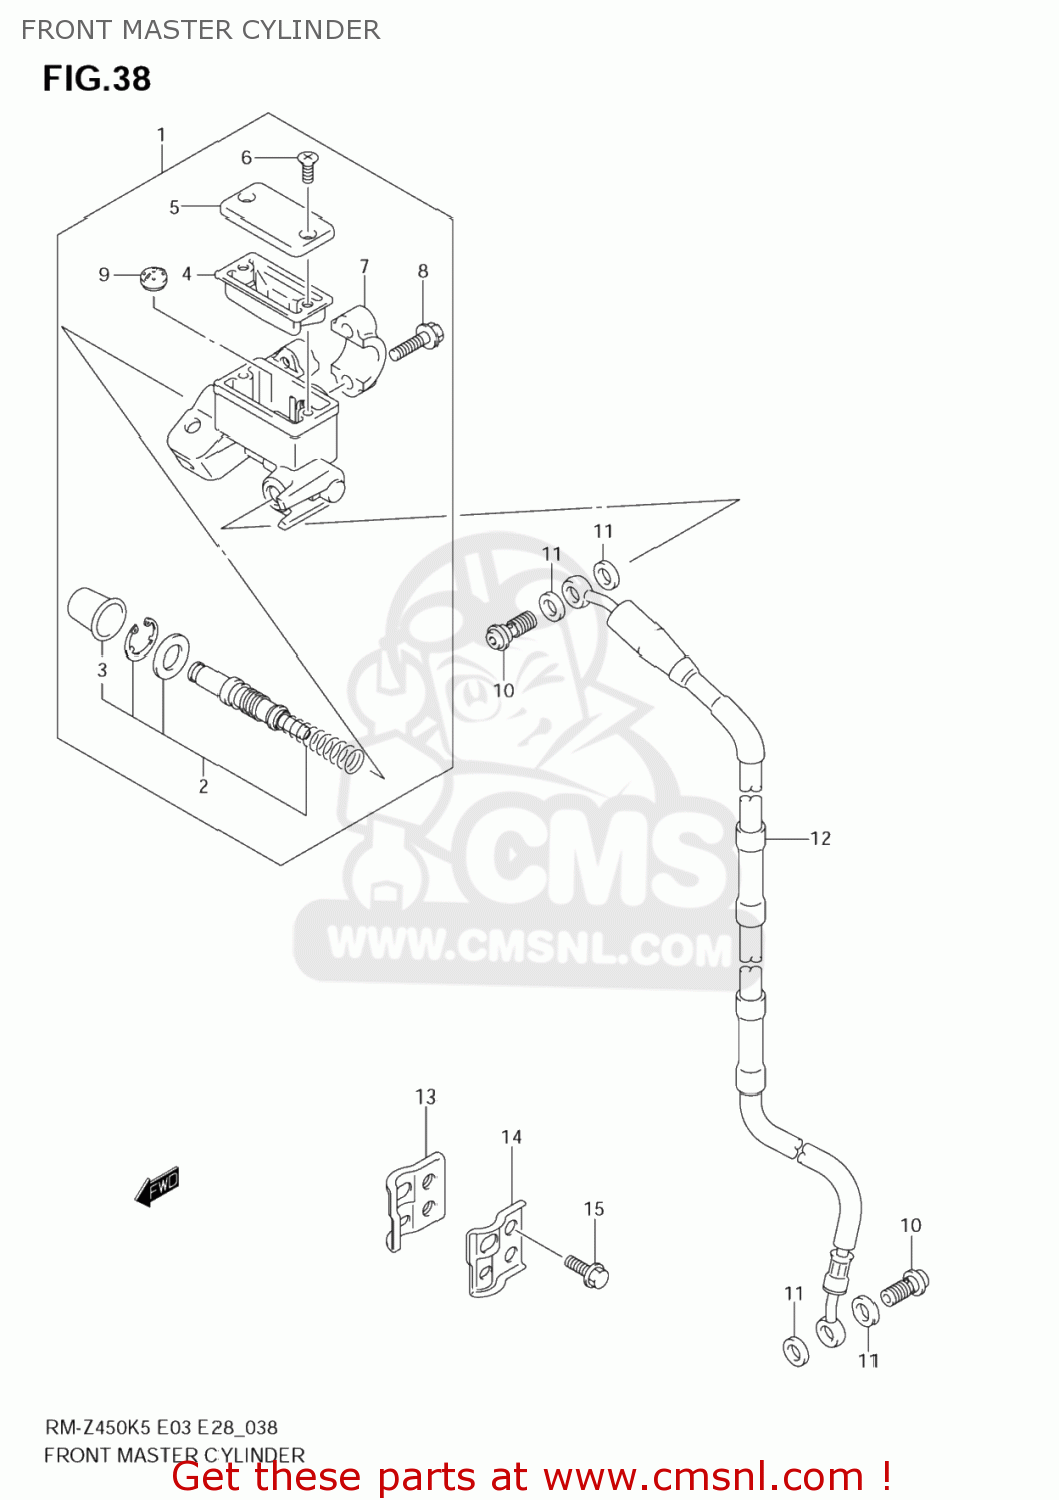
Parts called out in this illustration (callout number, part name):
1	CYLINDER ASSY,FR MASTER
2	PISTON & CUP SET
3	BOOT
4	DIAPHRAGM
5	CAP
6	SCREW
7	HOLDER
8	BOLT
9	SEPARATOR
10	BOLT UNION
11	WASHER(10X15X1.5)
12	HOSE,FRONT BRA
13	CLAMP,FR BRAKE HOSE INNER
14	CLAMP,FR BRAKE HOSE OUTER
15	BOLT(6X16)
